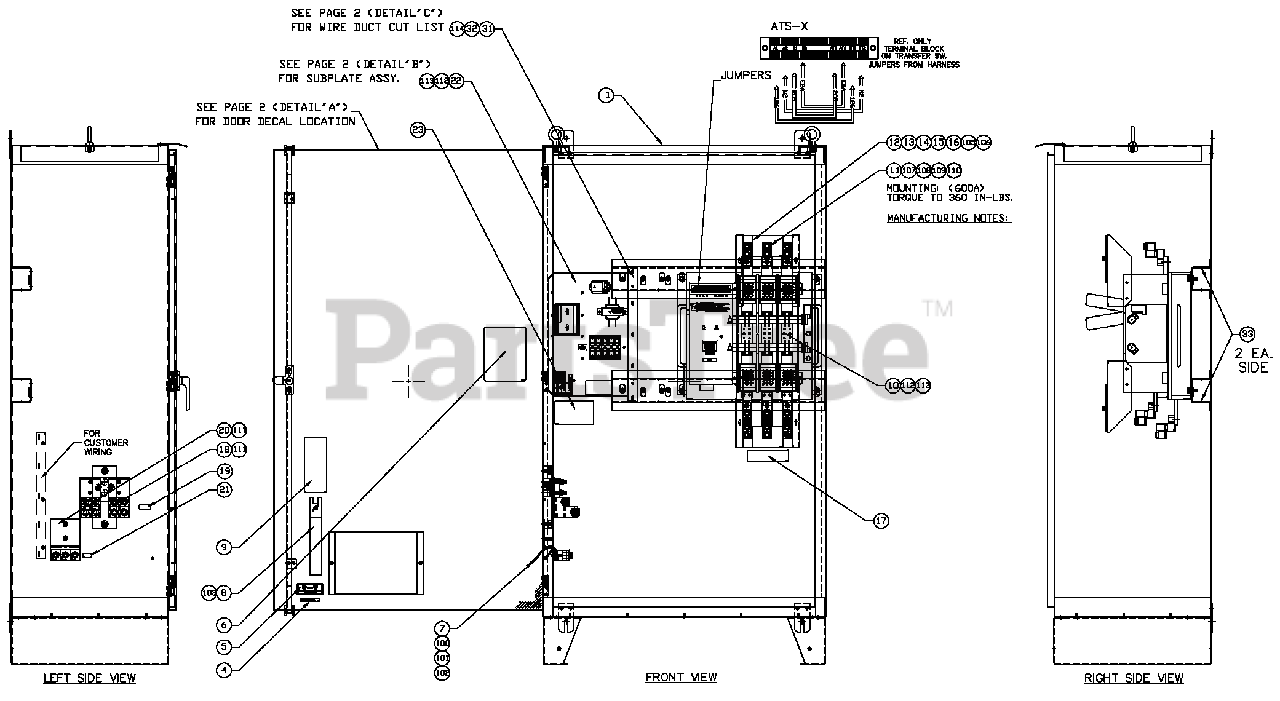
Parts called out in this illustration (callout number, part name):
1	ENCL NEMA 3R 36 X 60 X 20 RTS
4	DECAL ENCLOSURE NOTE NEMA 3R
5	DECAL, UL CONTROL PANEL ENCL.
6	DECAL RTS TEST SEQUENCE 600A
7	ASSY WIRE #0 12.00" (GROUND WIRE)
8	MNL HNDL 6-1600A WN (SUPPLIED W/ SWITCH)
9	DECAL MANUAL OPERATION
10	XFRSW 600A 3P WN600V
11	LUG SLDLSS 500- #1X13/32 AL/CU
12	SW CVR WN 600A 3P
13	CVR BKRT 600-1600A RH
14	CVR BKRT 600-1600A LH
15	KNOB, COVER HOLD-DOWN
16	DECAL TERMINAL SHOCK HAZARD
17	DECAL TERMINAL NOTE
18	ASSY NEUTRAL BLK 600-1000A ATS
19	DECAL NEUTRAL
20	ASSY GRD. TERM. 600-2600A
21	DECAL GROUND LUG
22	SUB-PLATE RTS 600-800A
23	PLATE DATA - RTS
31	DUCT WIRING 1 X 1.5 (17"LG)
32	COVER WIRE DUCT 1 IN (17"LG)
33	TIE-WRAP MOUNT(FIR TREE SYTLE)
100	WASHER FLAT #8 ZINC
101	WASHER LOCK #8-M4
102	NUT HEX M4-0.7 G8 YEL CHR
103	NUT WING M6-1.0
105	WASHER LOCK #10
106	SCREW HHTT #10-32 X 3/8 CZ
107	WASHER LOCK 1/2
108	NUT HEX 1/2-13 STEEL
109	SCREW HHC 1/2-13 X 4 G5
110	SCREW HHTT #8-32 X 1/4 CZ
111	NUT HEX FL WHIZ M8-1.25
112	SCREW HHC M10-1.5 X 30 G8.8
113	WASHER LOCK M10
114	RIVET WIRE DUCT MNT
